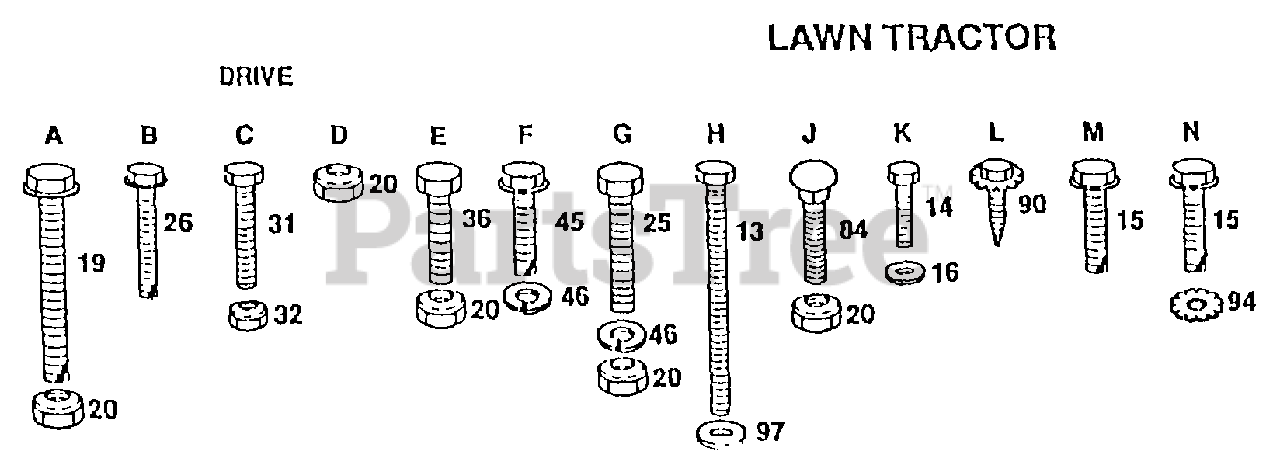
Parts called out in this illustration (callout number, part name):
13	"BOLT,HEX"
14	BOLT
15	SCREW
16	LOCKWASHER
19	BOLT
25	BOLT
26	SCREW
31	BOLT
45	SCREW
46	WASHER
84	BOLT
94	LOCKWASHER
97	WASHER T
